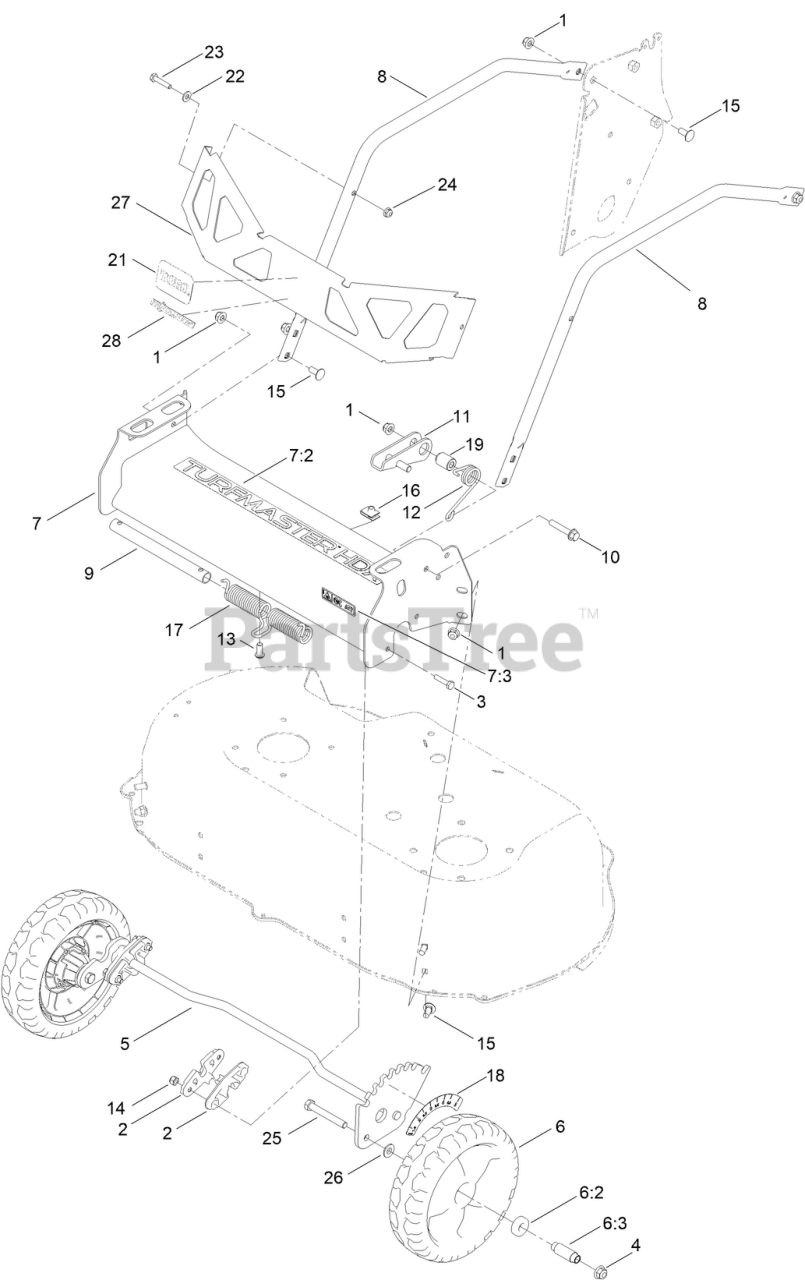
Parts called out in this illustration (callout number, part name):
1	NUT-HF, NI
2	BUSHING-FRONT
3	SCREW-HH
4	NUT-HF, NI
5	FRONT AXLE ASM
6:2	BEARING-BALL
6:3	SPACER
7	FRONT BUMPER ASM
7:3	DECAL-WARNING
9	MANDRELL-SPRING
10	SCREW-HWH
11	LOCK-HEIGHT, ADJ
12	SPRING-TORSION
13	SCREW-HSBH
14	NUT-LOCK, NI
15	SCREW-CARR
16	NUT-U
17	SPRING-TORSION
18	DECAL-HOC, FRONT
19	SPACER
21	DECAL-TORO, SILVER (2.75 X 1.8)
22	WASHER-FLAT
23	SCREW-HH
24	NUT-HF
25	SCREW-HH
26	SPACER-COVER, WHEEL
27	GUARD-ENGINE
28	DECAL-REVOLUTION
